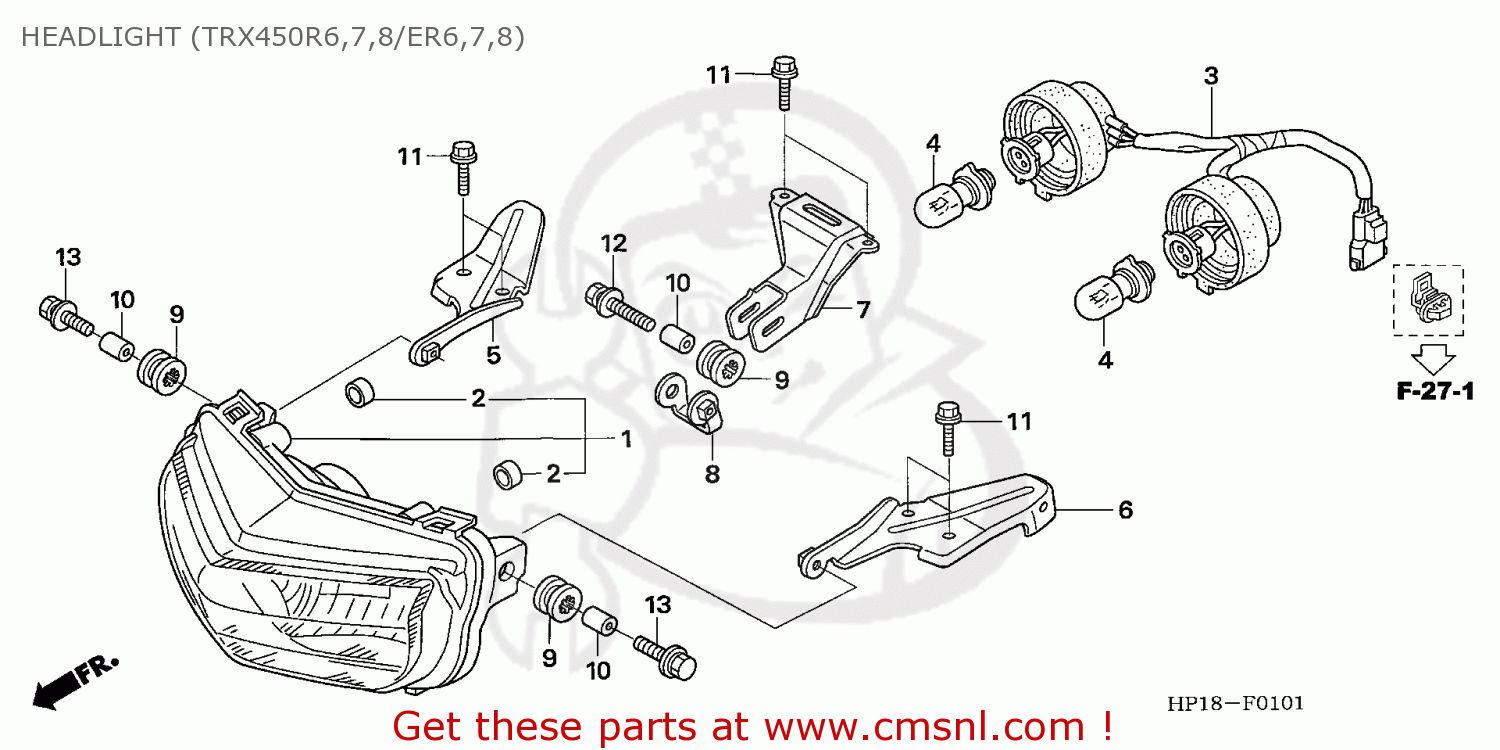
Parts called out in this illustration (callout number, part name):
1	UNIT COMP.HEAD LI
2	PIPE CP
3	SOCKET COMP.,HEAD
4	BULB,HEAD LIGHT
5	STAY,R HEAD LIGHT
6	STAY,L HEAD LIGHT
7	STAY,HD/LT LWR
8	PLATE,HD/LT LWR
9	RUBBER B,RR COWL
10	COLLAR,H/L MT
11	BOLT,FLANGE,NSHF,
12	BOLT,FLANGE,NSHF,
13	BOLT-WASH.,6X25
